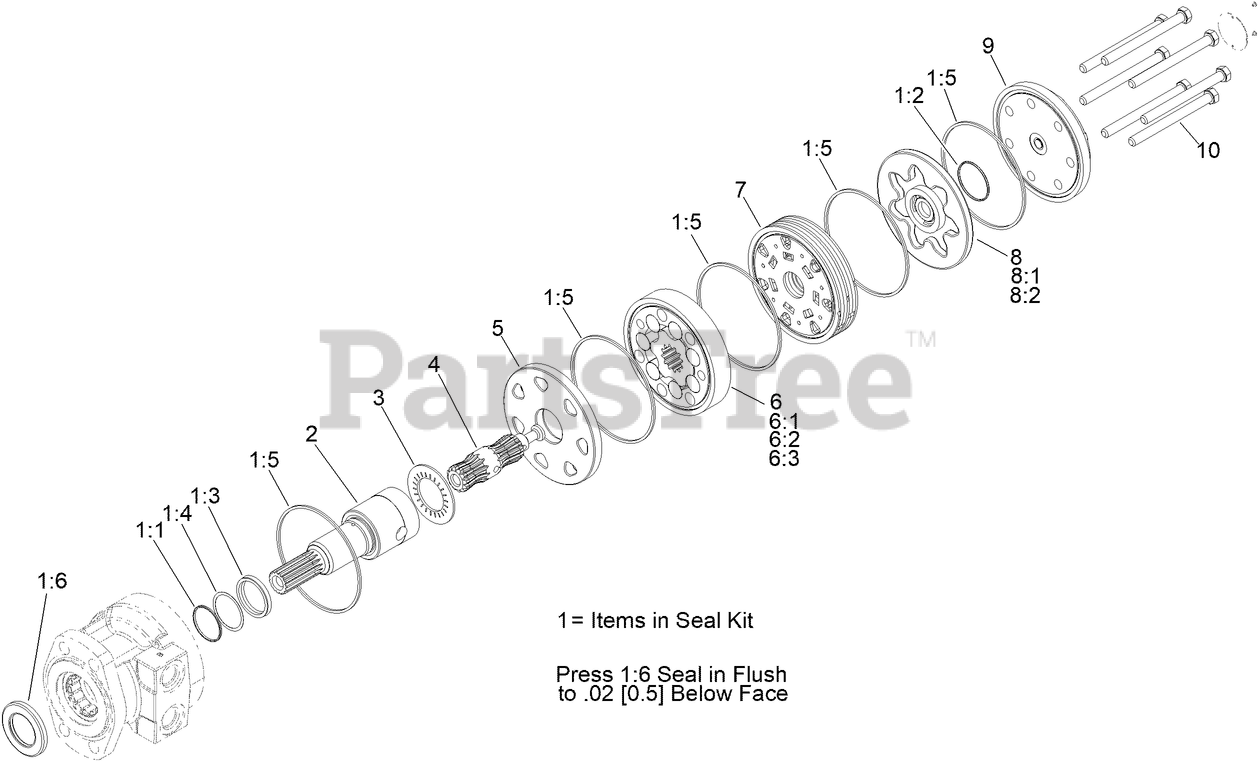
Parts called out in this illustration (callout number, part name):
1	SEAL KIT
1:1	RING-BACKUP
1:2	Seal-Commutator
1:3	SEAL-Shaft
1:4	Washer-Backup
1:5	Ring-Seal
1:6	Seal-Dirt and Water
2	Shaft-Coupling
3	BEARING-THRUST
4	LINK-DRIVE
5	PLATE-WEAR
6	ROTOR SET
6:1	Rotor
6:2	Vane
6:3	Stator
7	MANIFOLD
8	COMMUTATOR ASM
8:1	Commutator
8:2	Ring-Commutator
9	END COVER ASM
10	Bolt-Special
